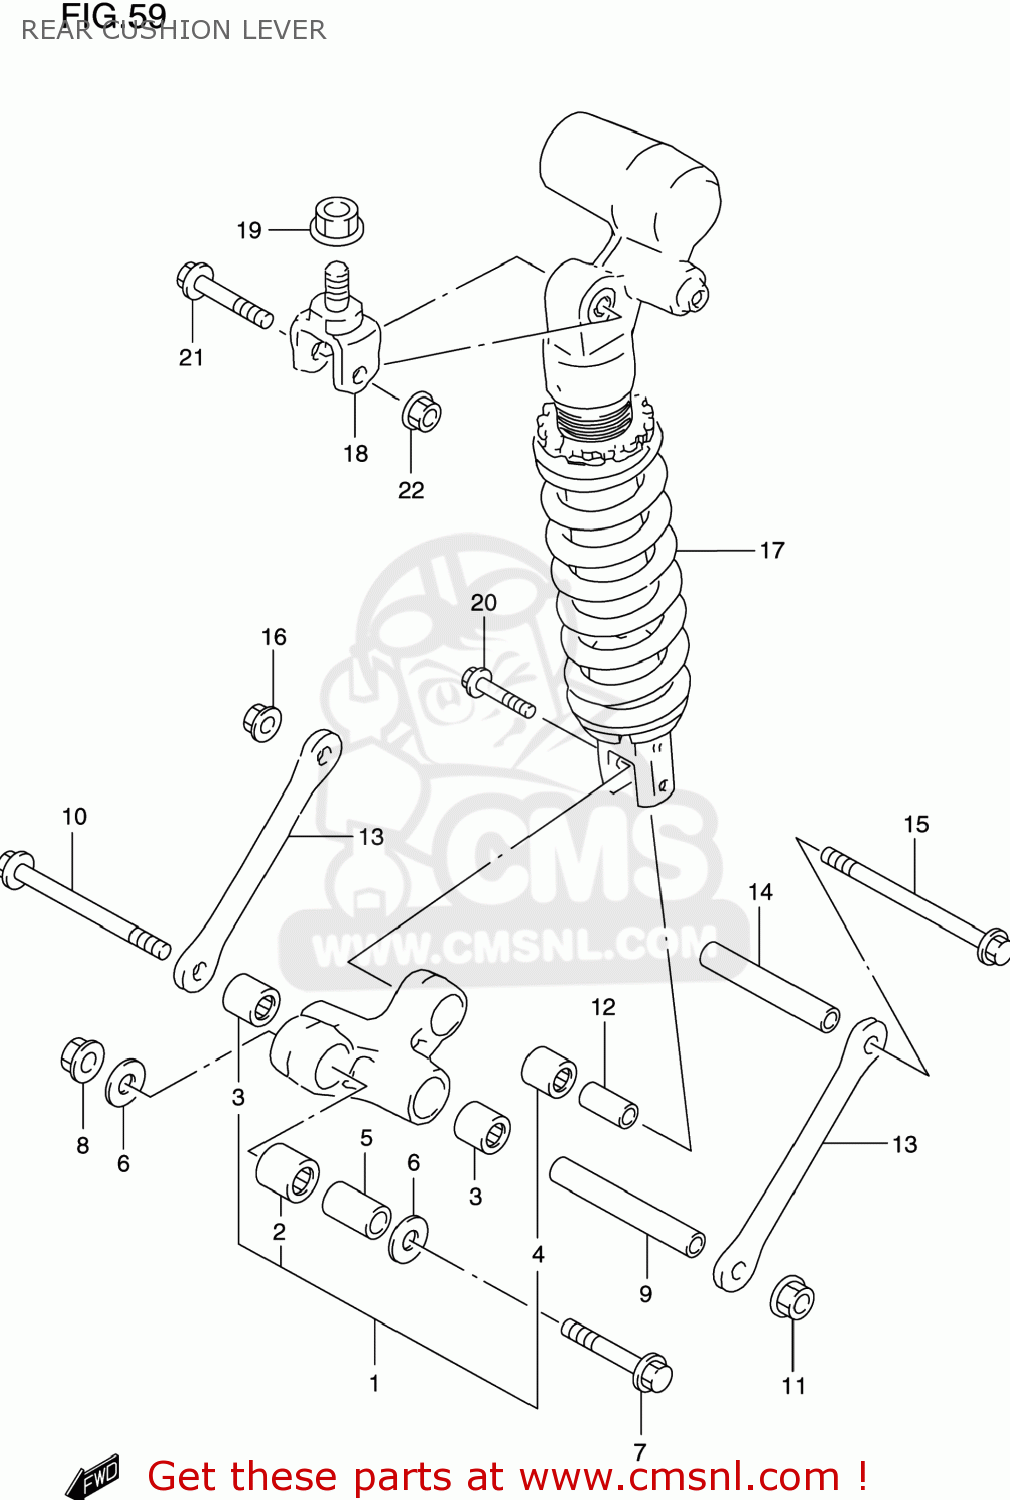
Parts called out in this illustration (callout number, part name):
1	LEVER SET,RR CUSHION
2	BEARING(20X27X30)
3	BEARING(17X24X20)
4	BEARING(17X24X26)
5	SPACER,RR CUSHION LEVER FR
6	WASHER
7	BOLT,RR CUSHION LEVER FR
8	NUT 12MM
9	SPACER,RR CUSHION LEVER CTR
10	BOLT,RR CUSHION LEVER CTR
11	NUT 12MM
12	SPACER,RR CUSHION LEVER
13	ROD,RR CUSHION LEVER
14	SPACER,RR CUSHION LEVER CTR
15	BOLT,RR CUSHION LEVER CTR
16	NUT 12MM
17	ABSORBER ASSEMBLY,REAR SHOCK
18	BRACKET,RR SHOCK ABSORBER UP
19	NUT
20	BOLT(10X44)
21	BOLT(10X54)
22	NUT
